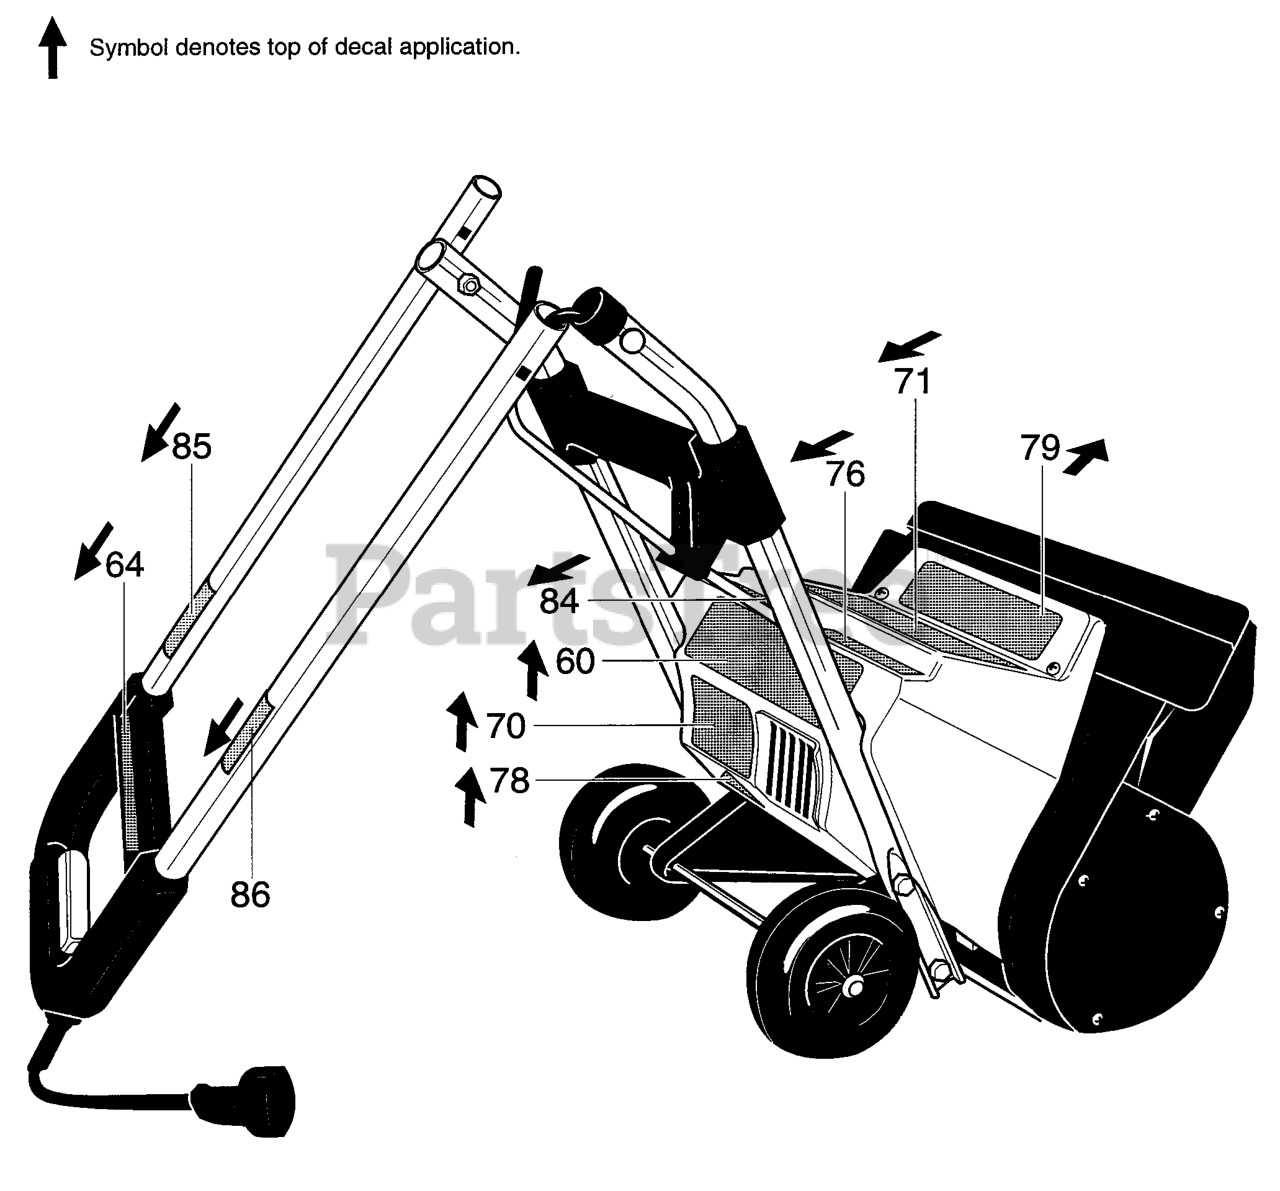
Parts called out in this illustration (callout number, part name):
60	DECAL, FOR SAFE OPERATION ENG/FR AUTOCOLLANT
64	DECAL TO START & STOP AUTOCOLLANT
70	NOT SERVICEABLE
71	DECAL, NAMEPLATE AUTOCOLLANT
76	DECAL, DISCHARGE CONTROL AUTOCOLLANT
79	DECAL, DANGER FOOT AUTOCOLLANT
84	DECAL,WARNING CUT-OUT AUTOCOLLANT
85	DECAL, MOTOR PROTECTION, ENG AUTOCOLLANT
86	DECAL, MOTOR PROTECTION, FR AUTOCOLLANT
